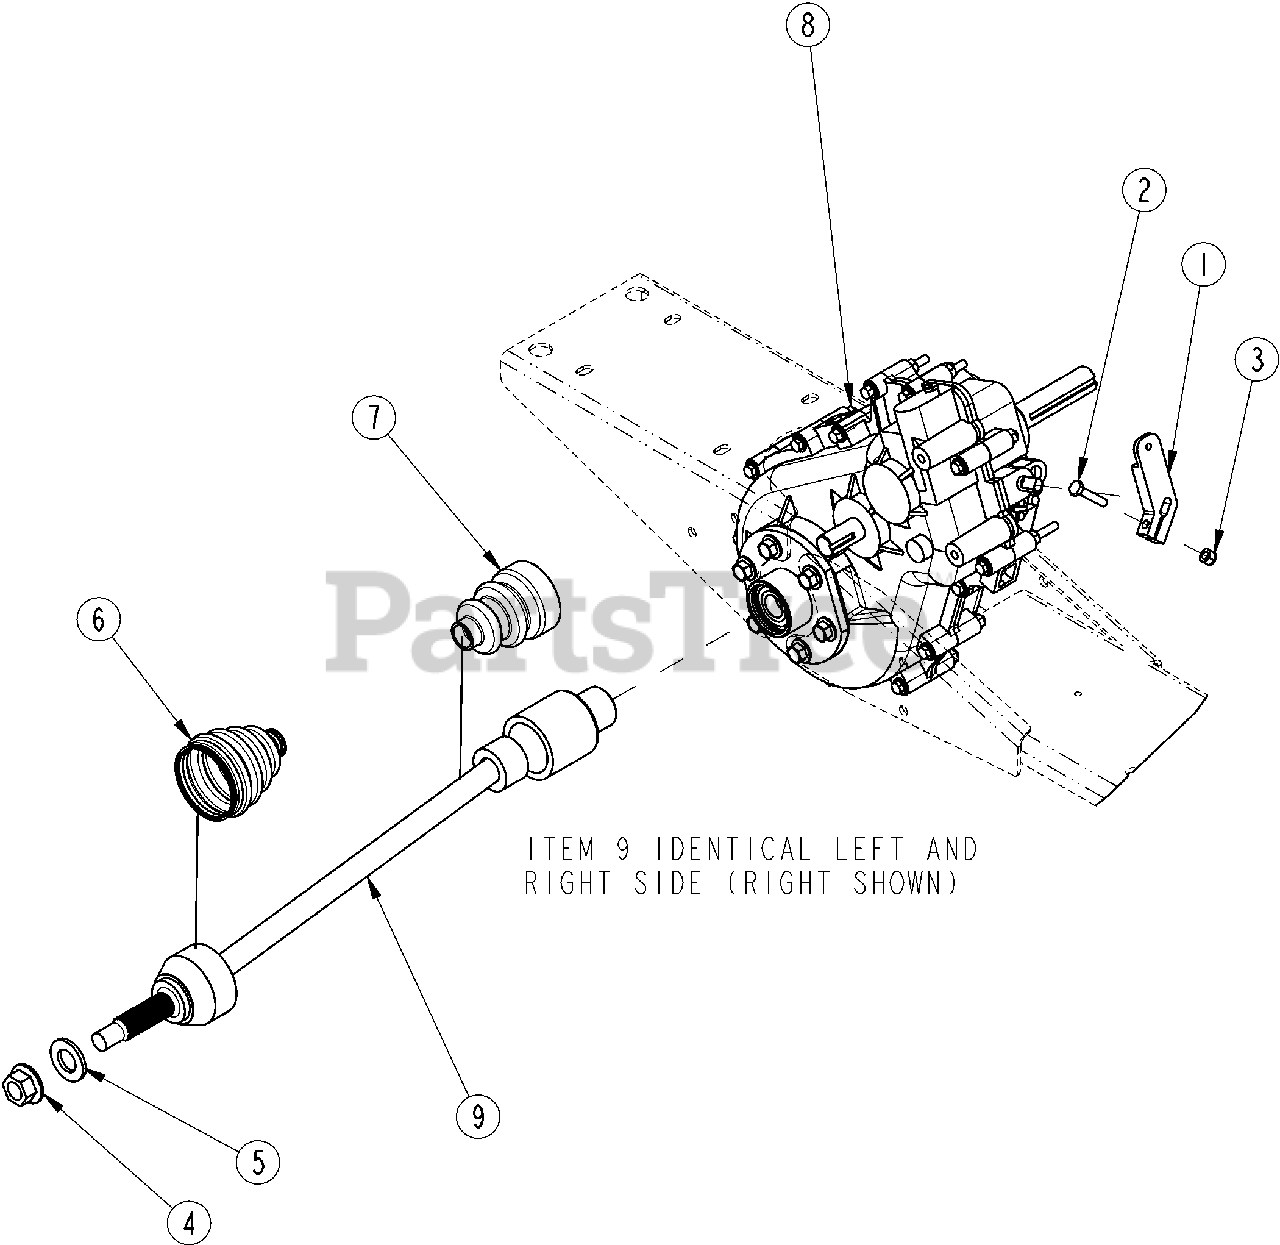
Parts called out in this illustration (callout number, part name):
1	SHIFT LEVER
2	HHCS 1/4-20X1 1/4 GR8
3	NUT HEX NYLOCK 1/4-20
4	NUT HEX M16X1.5 TOP LOCK PLT
5	WASHER FLAT 3/4 SAE PLT
6	OUTER BOOT KIT W/ 2 CLAMPS
7	INNER BOOT KIT W/2 CLAMPS
8	TRANSAXLE W/ AUTO-LOCK DIFF.
9	REAR AXLE SHFT ST, 24T INT.SPL
